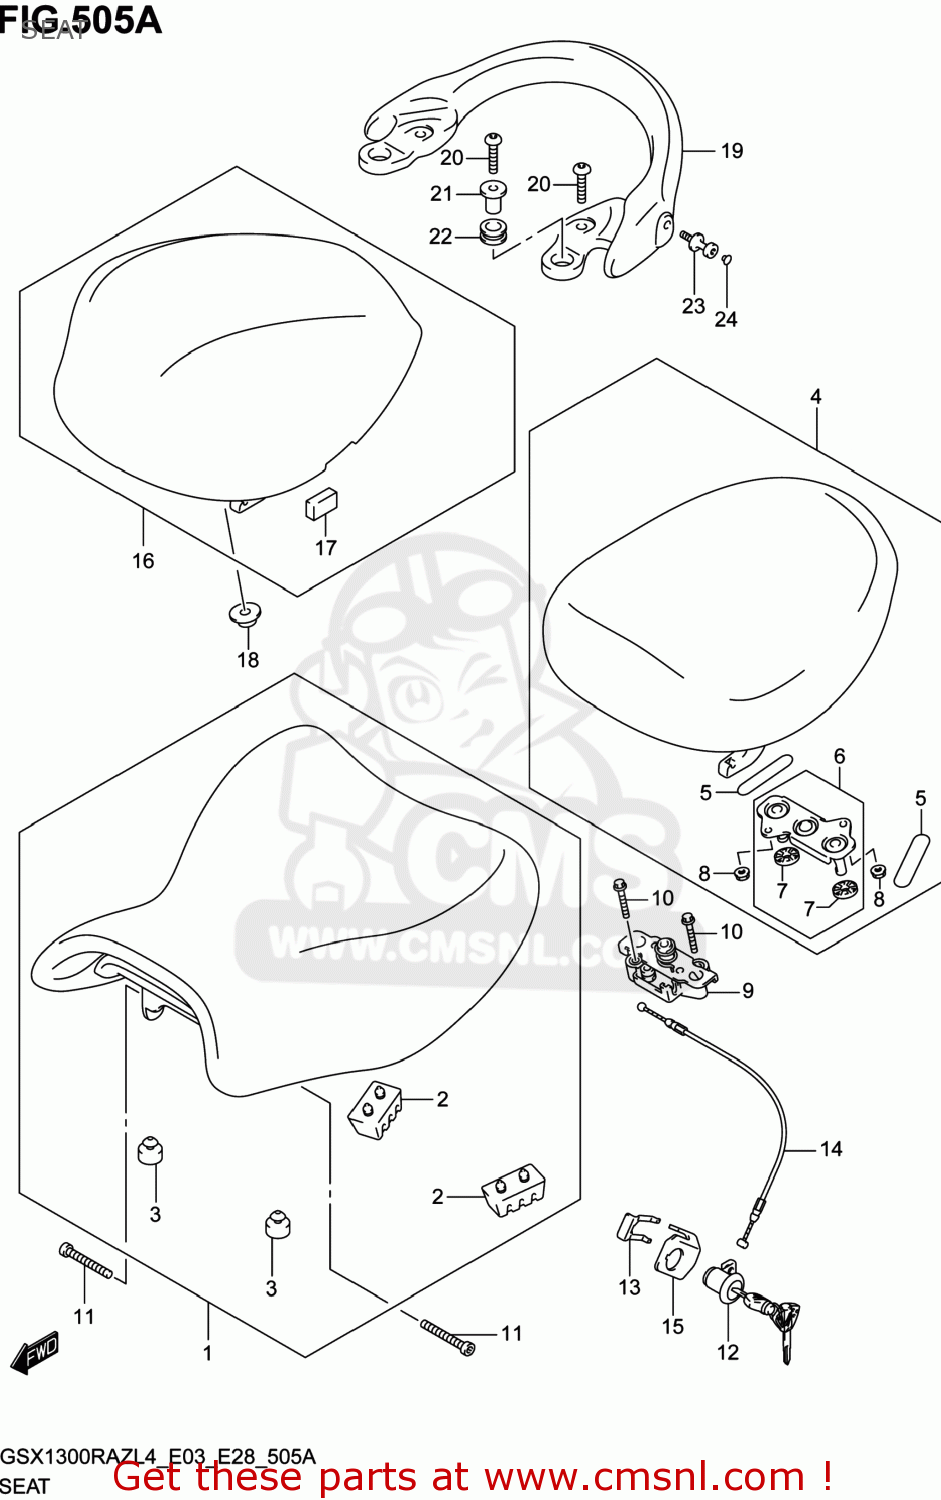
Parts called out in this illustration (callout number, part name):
1	SEAT ASSY
2	CUSHION,SUPPORT(50X25X32)
3	CUSHION
4	SEAT ASSY,PILLION
5	CUSHION
6	STRIKER,SEAT LOCK
7	CUSHION
8	NUT
9	BRACKET,STRIKER SUPPORT
10	BOLT
11	BOLT,SEAT FR
12	LOCK SET,SEAT
13	PLATE,SEAT LOCK ASSY
14	CABLE,SEAT LOCK
15	GUIDE,SEAT LOCK CABLE
16	BOX,SEAT TAIL(BLACK)
17	CUSHION
18	WASHER,FRAME COVER
19	HANDLE,PILLION RIDER
20	BOLT(8X33)
21	WASHER,PILLION
22	CUSHION,PILLION RIDER HANDLE
23	HOOK,PILLION RIDER HANDLE
24	CAP(OD:10)
